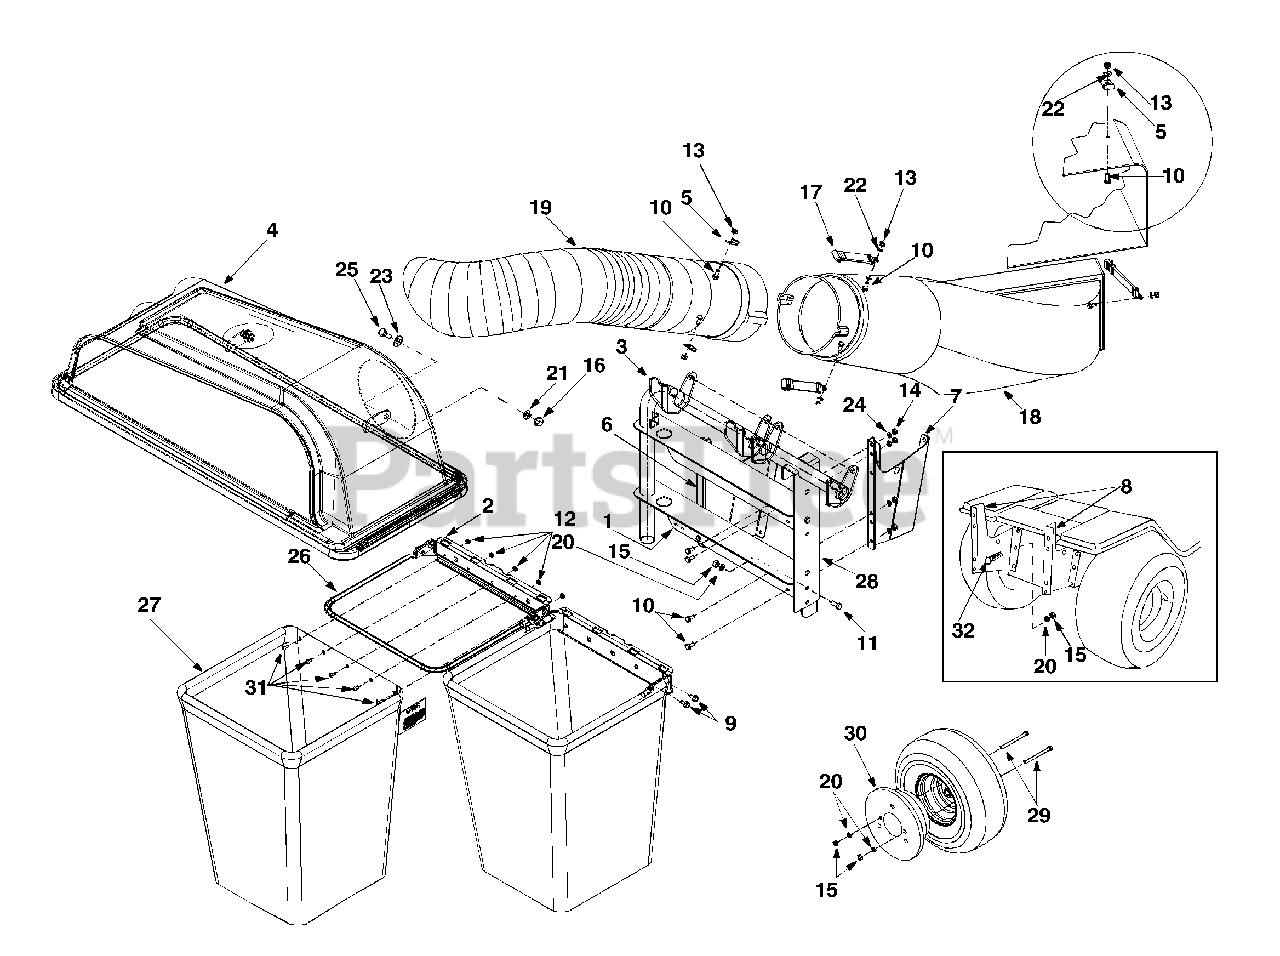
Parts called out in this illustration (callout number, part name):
4	Cover Assembly
5	Retainer Hook Bracket
9	Screw, TT: 5/16-18 X 0.625"
10	Hex Bolt: 1/4-20 X 0.620" Gr. 5
11	Hex Bolt: 5/16-18 X 0.75" Gr. 5
12	Hex Sems Nut: 10-24
13	Hex Lock Nut
14	Hex Nut: Gr. 5
15	Hex Nut: 5/16-18
16	Hex Nut: 3/8-16 Gr. 8
17	Retainer Strap Assembly
18	Discharge Chute
19	Chute Tube
20	Lock Washer: 5/16
21	Lock Washer
22	Spring Washer
23	Bell Washer
24	Lock Washer: 1/4
25	Shoulder Screw
27	Catcher Bag
29	Hex Bolt 5/16-18 x 4.0" Gr.5
32	Hex Bolt: 5/16-18 x 0.75"
